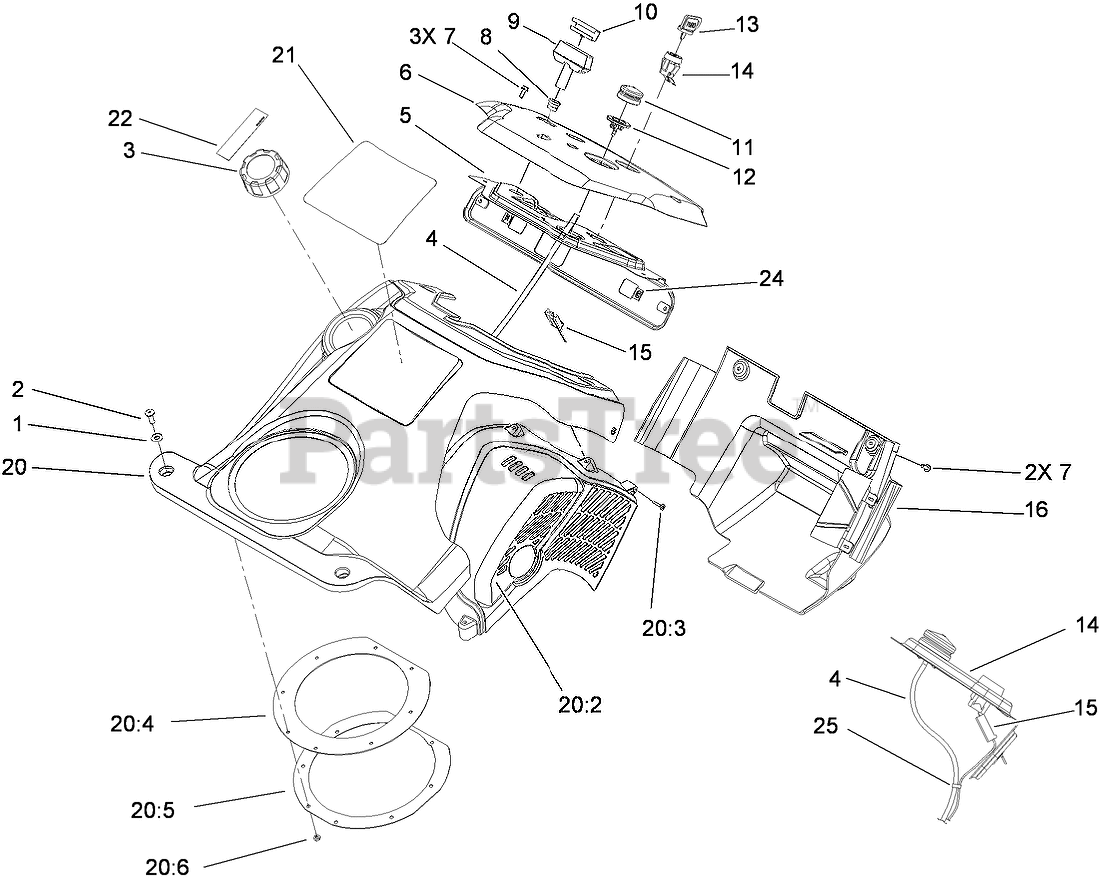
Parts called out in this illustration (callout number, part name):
1	WASHER-FLAT
2	SCREW-PPH
3	GAS CAP ASM
4	HOSE-PRIMER
5	PANEL-SUPPORT, CONTROL
6	PANEL-CONTROL
7	SCREW-HWH
8	GUIDE-ROPE, STARTER
9	HANDLE-START
10	CLIP-STARTER
11	BULB-PRIMER
12	BODY-PRIMER
13	KEY-IGNITION
14	SWITCH
15	CONNECTOR-BODY
16	LOWER SHROUD/BAFFLE ASM
20	UPPER SHROUD ASM
20:2	SHIELD-HEAT
20:3	SCREW-PPH
20:4	Seal-Chute
20:5	RETAINER-SEAL, CHUTE
20:6	PALNUT
22	TAPE-MIX, OIL
24	NUT-SPEED
25	TIE-CABLE
